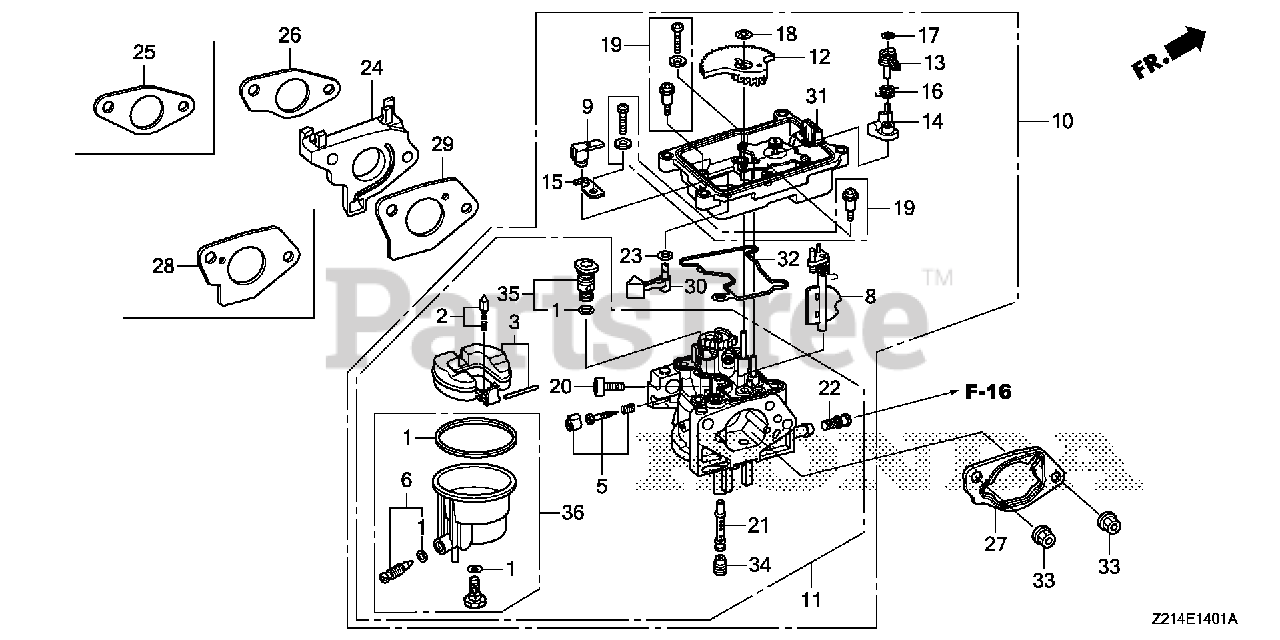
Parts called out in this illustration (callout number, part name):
1	GASKET SET
2	VALVE SET, FLOAT
4	CHAMBER SET, FLOAT
5	SCREW SET, PILOT
6	SCREW SET, DRAIN
7	BOLT KIT, FUEL CHAMBER
7	SCREW SET
9	ARM, MANUAL START
10	CARBURETOR ASSY. (BE96A A)
11	CARBURETOR SET
12	GEAR, MIDDLE
13	ARM, CHOKE
14	LEVER, CHOKE CONTROL
16	SPRING, TORSION COIL
17	CLIP, SPECIAL
18	CLIP, SPECIAL
20	SCREW, STOP
21	NOZZLE, MAIN
22	SCREEN, FUEL STRAINER
23	O-RING (4.8X1.9)
24	INSULATOR, CARBURETOR
26	GASKET, CARBURETOR INSULATOR
27	SPACER, CARBURETOR
29	GASKET, CARBURETOR
30	LEVER, MANUAL START
31	CASE, MOTOR
33	NUT, FLANGE (6MM)
34	JET, MAIN (#98)
34	JET, MAIN (#102)
34	JET, MAIN (#105)
35	JET SET, PILOT (#45)
36	BOLT KIT, FUEL CHAMBER
